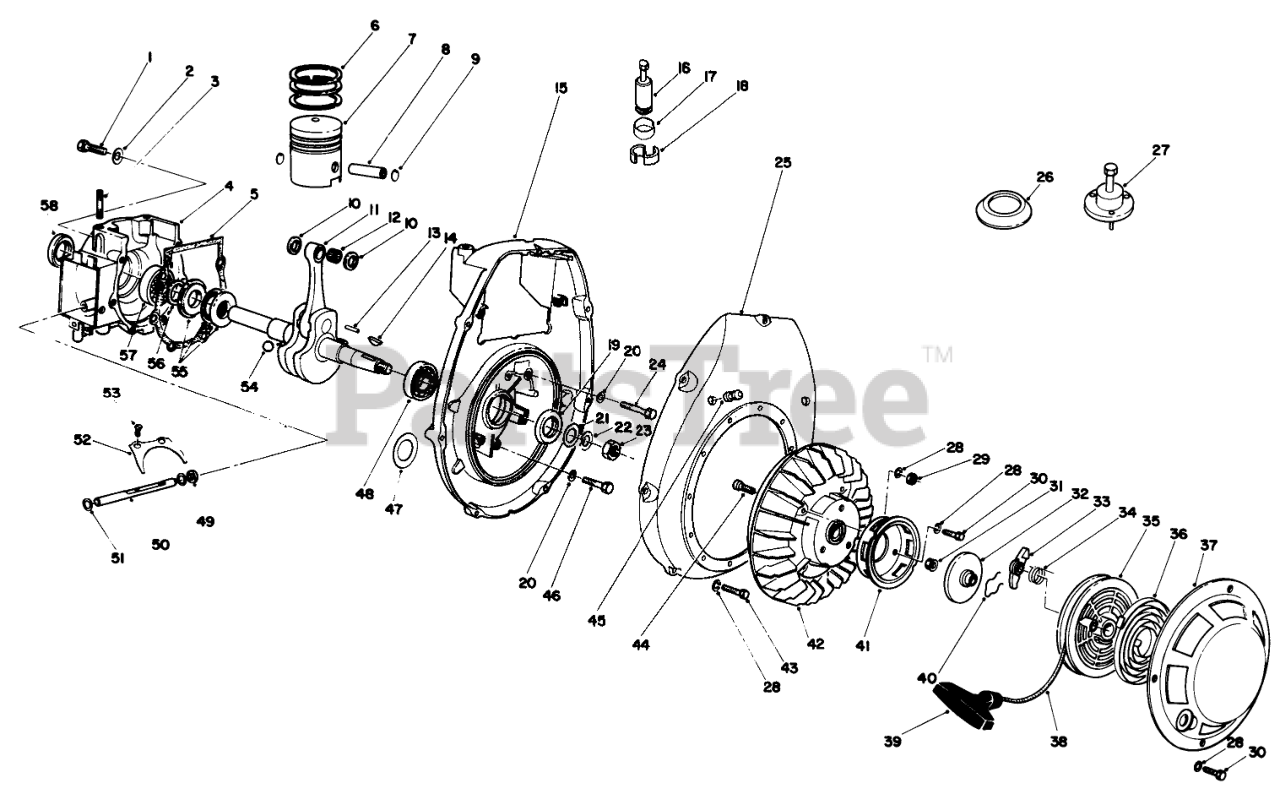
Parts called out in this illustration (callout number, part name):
1	Screw-Hex Head
2	Washer
4	Crankcase-PTO Side
5	CRANKCASE GASKET
6	Piston Rings
7	Pistons
8	Wrist Pin
9	Locking Ring
10	Washer
11	Crankshaft Assembly
12	Bearing-Needle
13	Needle
14	Key-Woodruff
15	Crankcase
16	Extractor
17	Retaining Ring
18	Half Bushes (Pair)
19	Oil Seal
20	Lockwasher
21	Washer
22	Washer
24	Capscrew-Hex Hd.
25	Cover-Fan
26	Meter-Revolution Frequency
27	Puller
28	Lockwasher
30	Screw-Hex Head
32	Brake-Disc
34	Spring
35	Pulley-Rope
36	Recoil Spring
37	Housing-Starter
38	Rope (Incl. Ref. #39)
39	Handle
40	SPRING
41	Carrier
42	Fan Wheel
43	HEX HEAD SCREW
44	Screw
46	Screw-Hex Head
47	Washer
48	Ball Bearing
49	Seal-Oil
50	Shaft-Governor
51	Washer
52	Fork-Governor
53	Screw
55	Needle Bearing Assembly
56	Washer
57	Ball Bearing
58	Oil Seal
